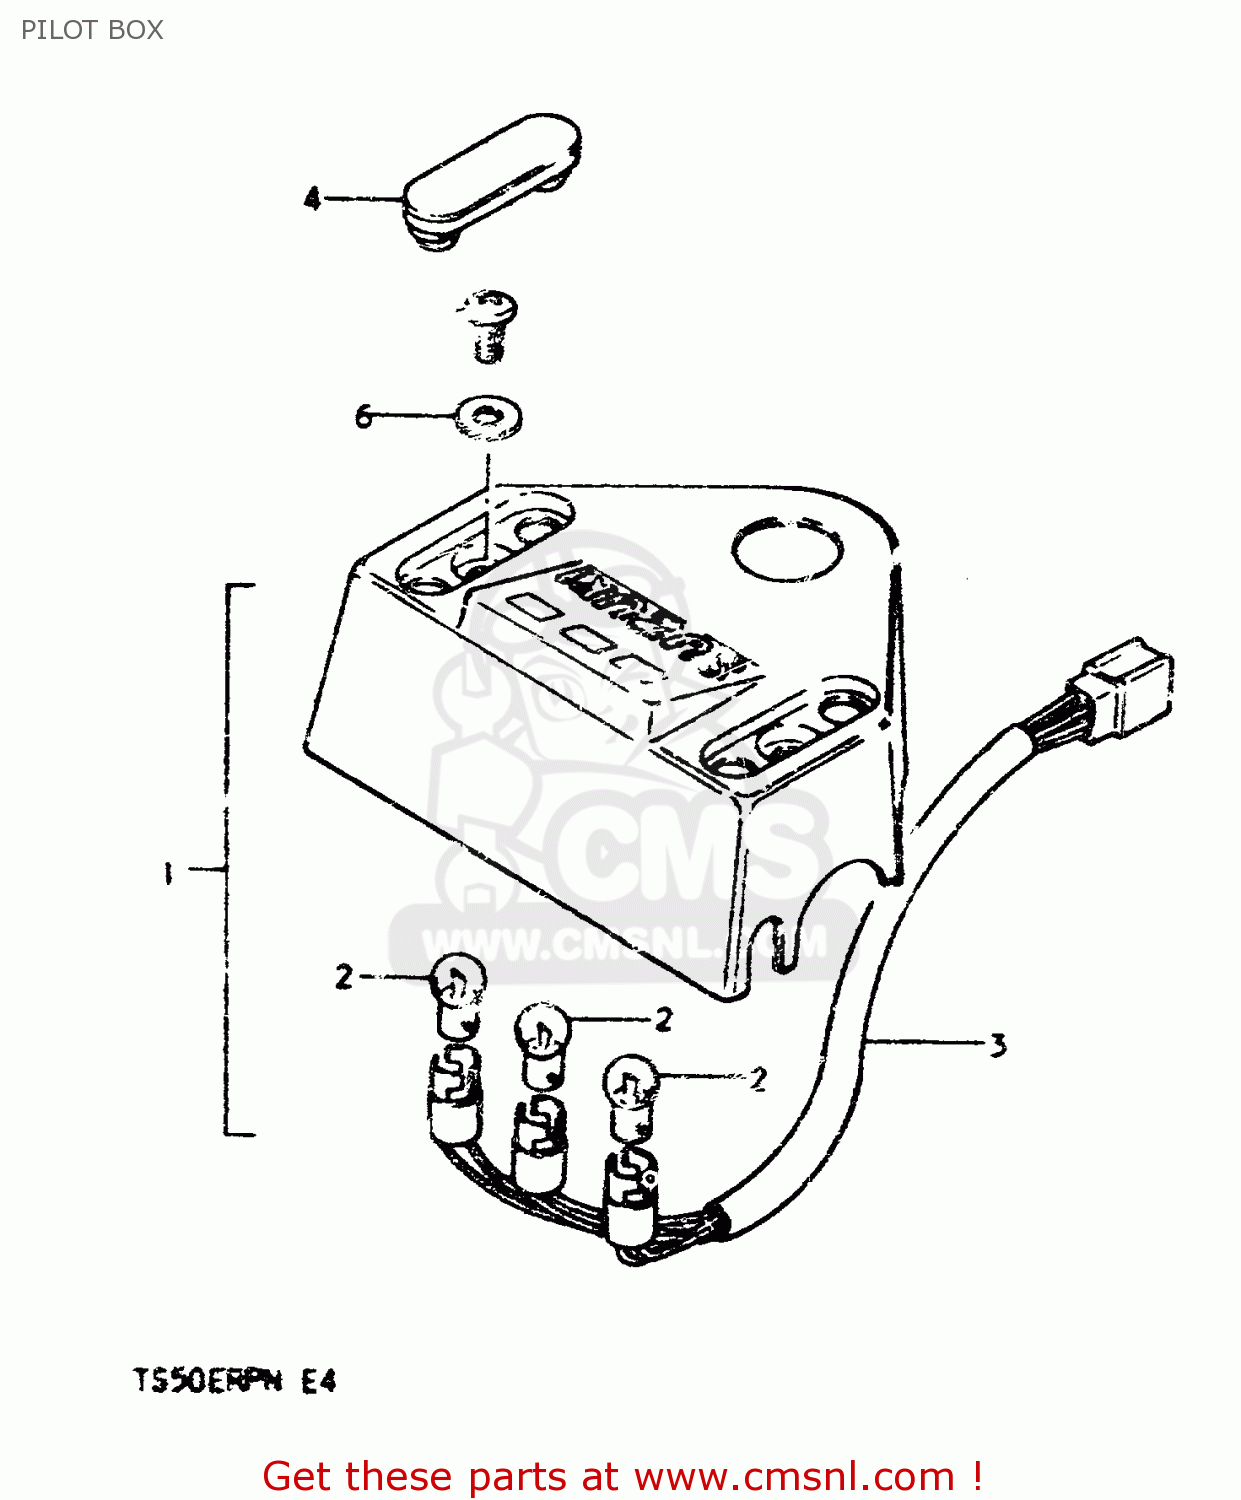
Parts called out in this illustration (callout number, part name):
1	PILOT BOX ASSY
2	BULB(6V/3W)
3	SOCKET
4	CAP,PILOT BOX BOLT
5	SCREW 6X12
6	WASHER
